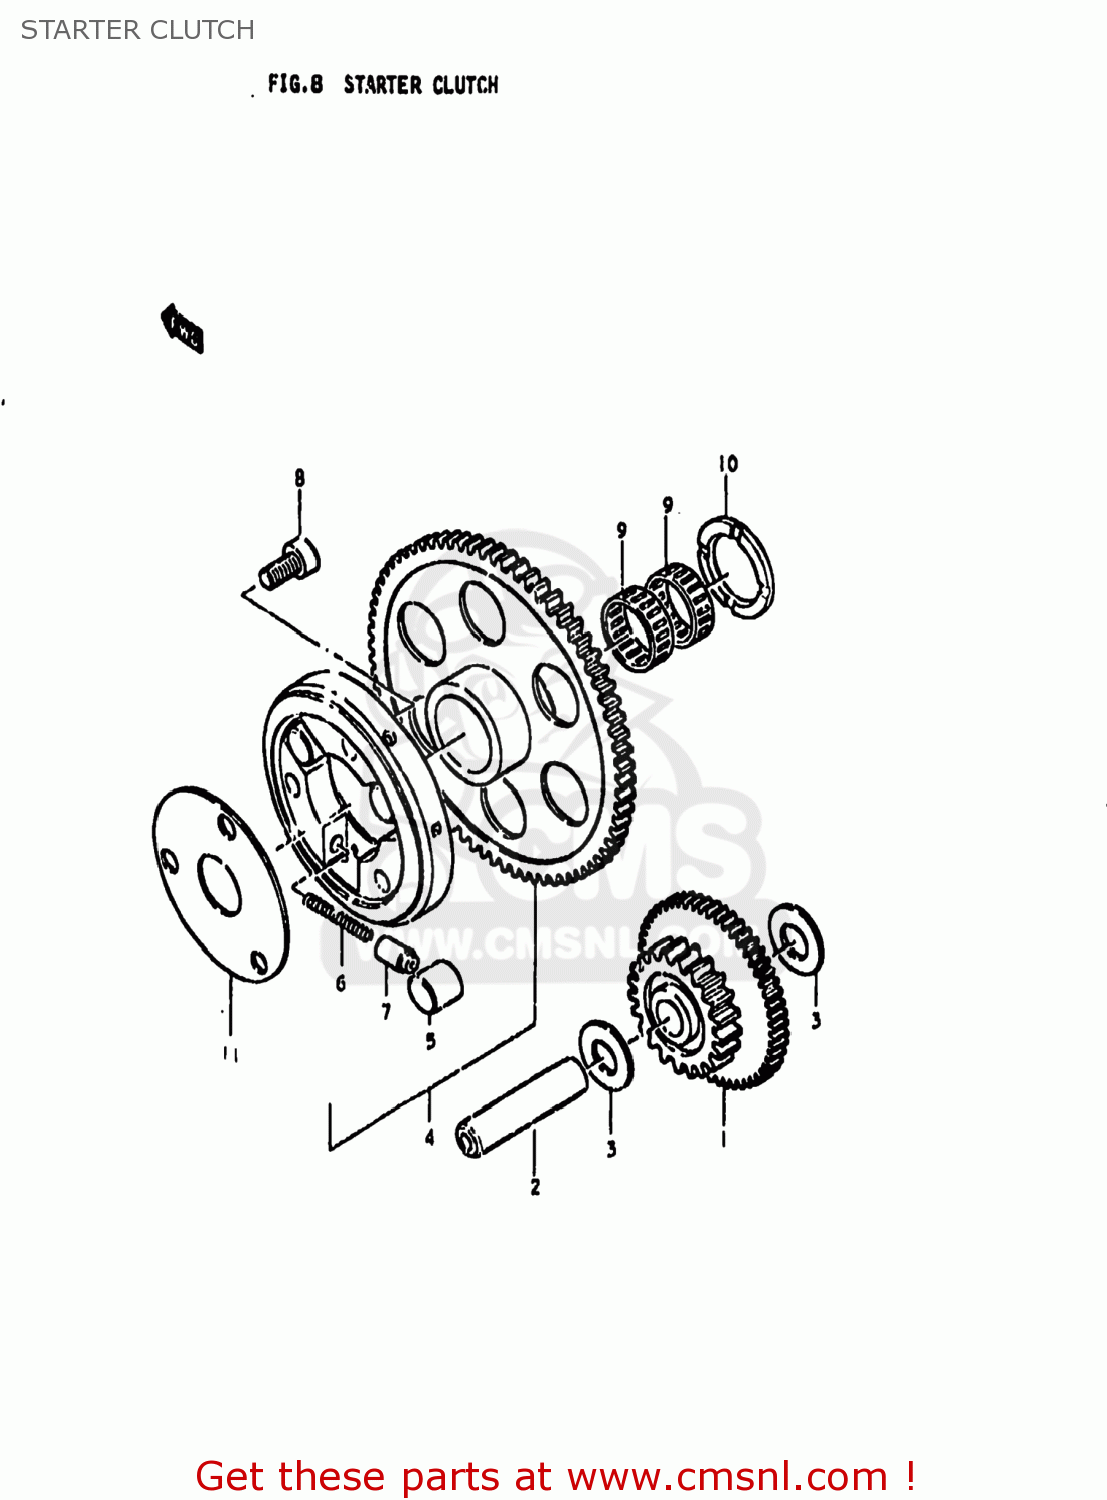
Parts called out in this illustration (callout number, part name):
1	GEAR,STARTER IDLE
2	PIN(7.4X13X56)
3	WASHER(13.3X25X0.85)
4	CLUTCH SET,STARTER
5	ROLLER(15X13)
6	SPRING
7	PIECE,PUSH
8	BOLT
9	BEARING(25X29X9.9)
10	WASHER(25X38X2.5)
11	SHIM,STARTER CLUTCH HUB
